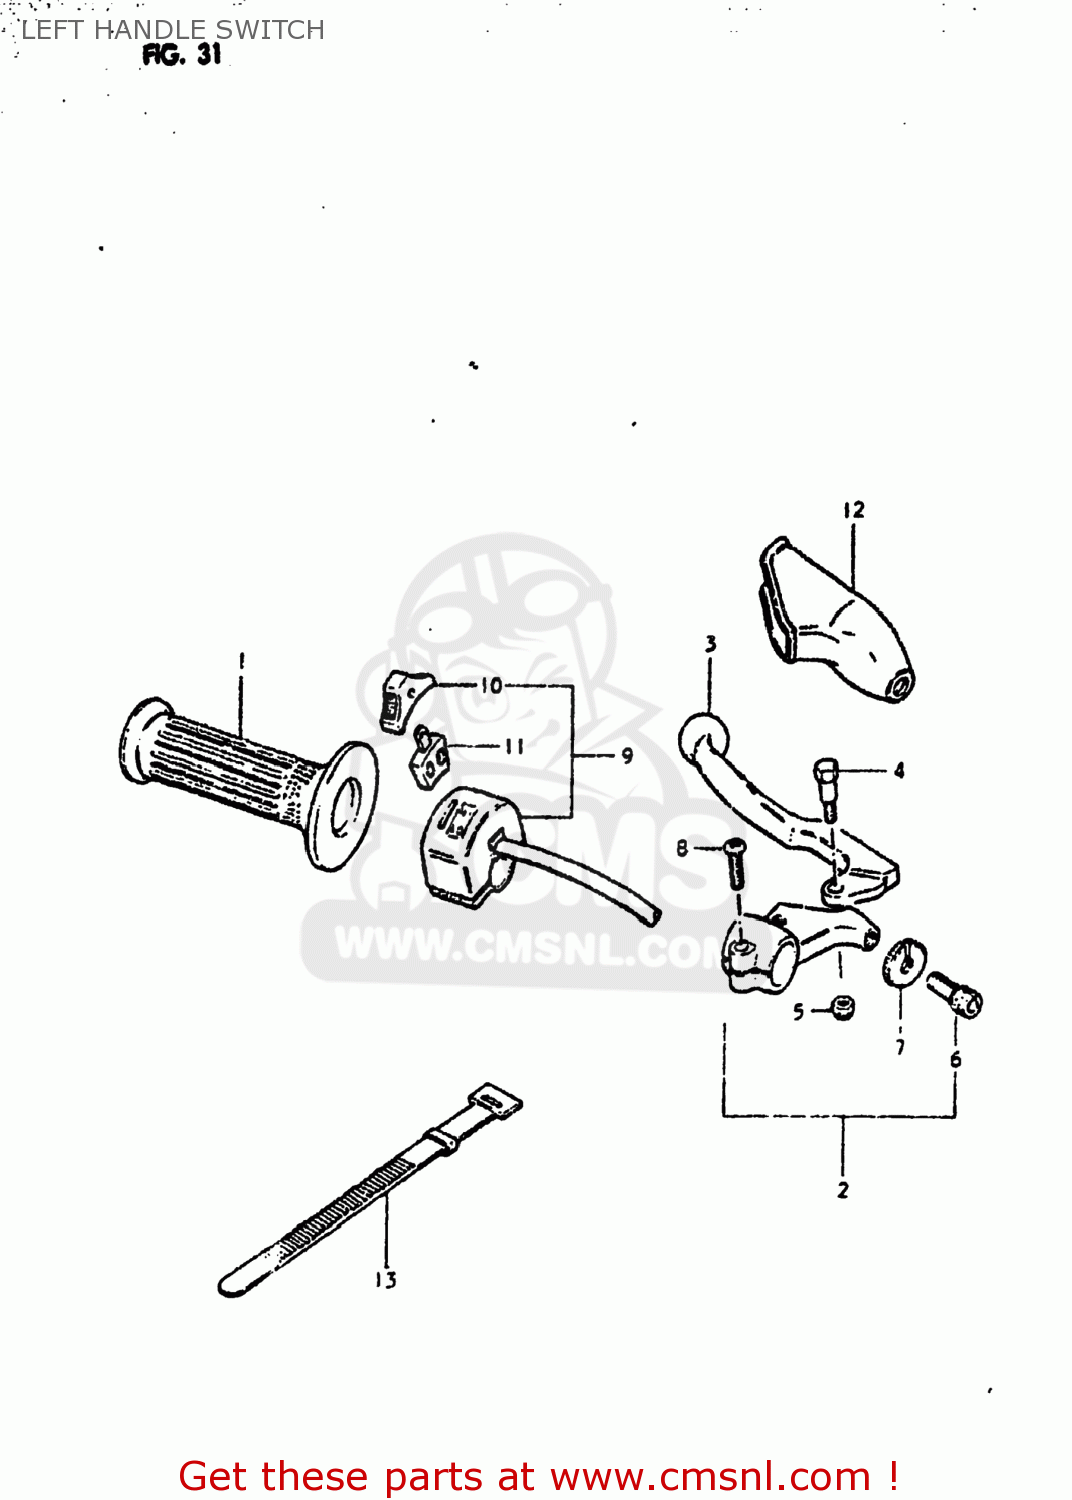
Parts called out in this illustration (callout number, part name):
1	GRIP,L
2	LEVER ASSEMBLY,CLUTCH
3	LEVER,CLUTCH
4	BOLT,LEVER
5	NUT 6MM
6	ADJUSTER,CABLE
7	NUT,CABLE ADJUSTER
8	SCREW
9	SWITCH,DIMMER
10	KNOB,LIGHTING & DIMMER
11	BLOCK,LIGHTING/DIMMER
12	COVER,CLUTCH LEVER
13	CLAMP(L:120)
